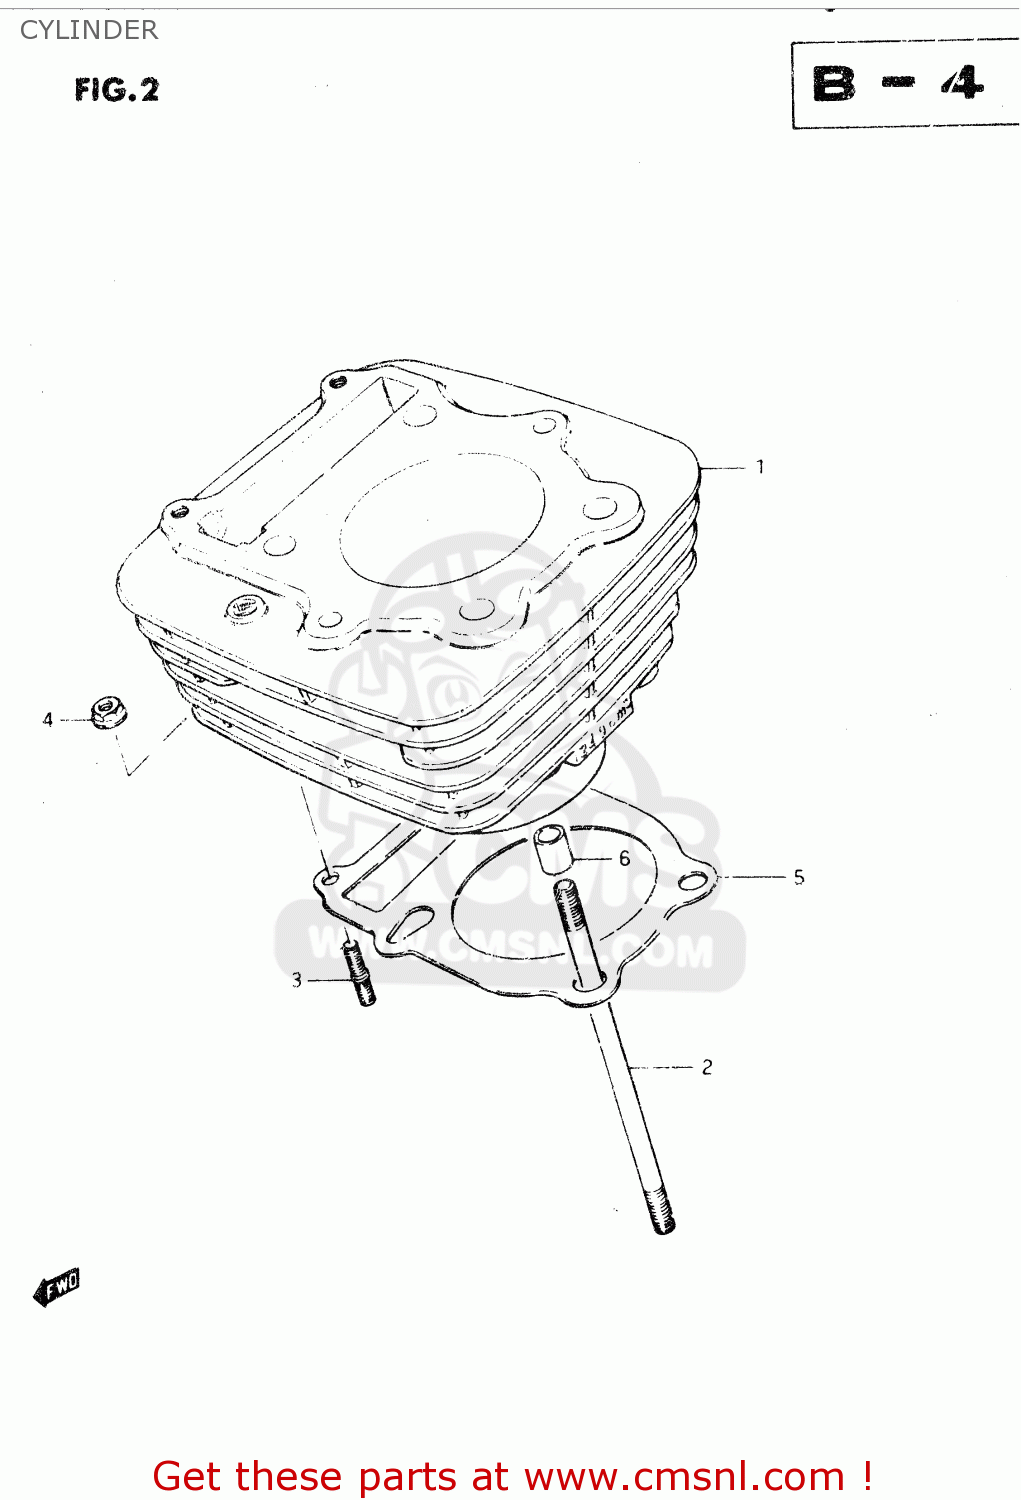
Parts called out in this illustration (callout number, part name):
1	CYLINDER
2	BOLT,STUD
3	STUD 6X25
4	NUT
5	GASKET,CYLINDER (MCA)
6	PIN
